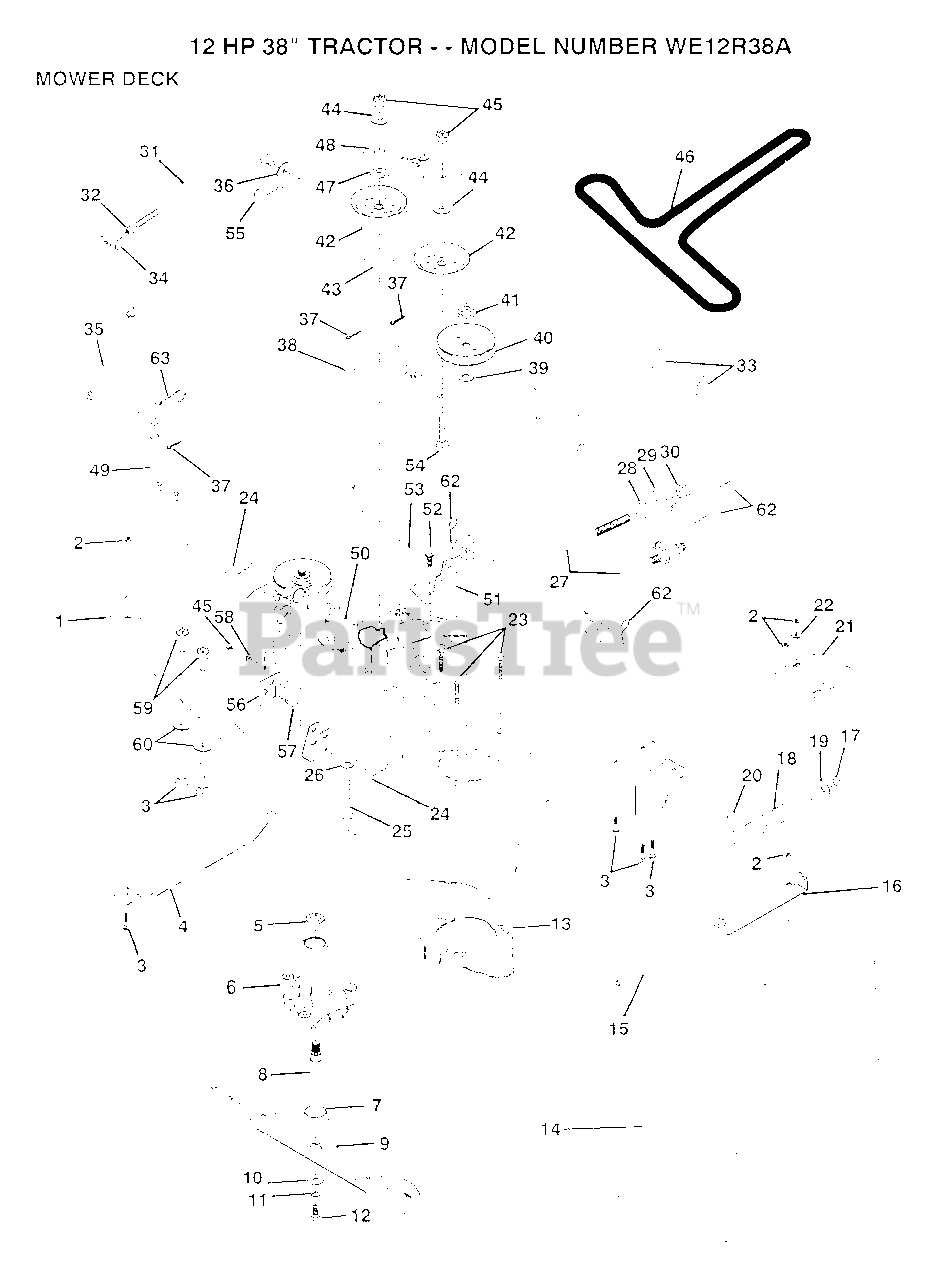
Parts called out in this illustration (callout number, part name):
3	BOLT
4	RUNNER-LH M
5	BEARING
6	HSG ASM MANDREL
7	BEARING.BALL
9	"BLADE.38"" HIPERF"
10	WASHER BLADE
12	BLADE BOLT
14	DEFLECTOR-SHLD T
15	ROD-HINGE T
16	BRKT DEFLECTOR
17	NUT PUSH M
18	SPRING TORSION
19	WASHER
20	CAP-SLEEVE LT
21	RUNNER RH
22	WASHER M
25	BOLT
26	WASHER GT
27	"LINK ASM.,FRONT"
28	NUT
29	TRUNION
30	NUT.LK.W/WSH.1/2.
31	CLUTCH ROD PRI
32	NUT
33	SUSP ARM REAR
34	TRUNNION
35	CLUTCH ROD SEC
36	WASHER
38	IDLER ARM ASSY
39	WASHER
42	FLAT IDLER PULLEY
43	SPACER RETAINER
44	WASHER GT
46	BELT-V.88.12.MW
47	RETAINER SPACER
48	IDLER ARM STIFF
49	PIVOT ROD
50	BRAKE ROD LH
51	BRAKE ASM
52	SCREW
53	BRAKE ROD RH
54	BOLT
55	SPRING.RETAINER
56	PLATE ADJ LINK LH
57	BOLT
58	WASHER T
59	NUT
60	WASHER.34X.68X16
62	RETAINER.SPRING
63	RETAINER M
